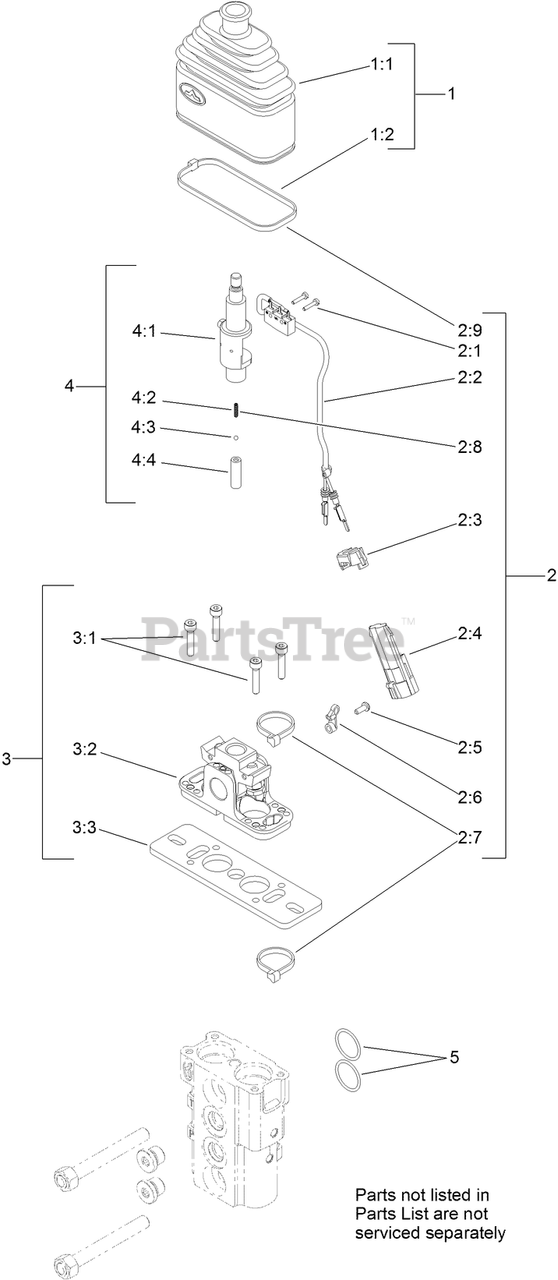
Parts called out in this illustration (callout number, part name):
1	BELLOW KIT
1:1	BELLOW-RUBBER
1:2	HUB and BEARING ASM
2	LIMIT SWITCH KIT
2:1	HUB and BEARING ASM
2:2	Switch
2:3	FAIRLEAD
2:4	Connector
2:5	HUB and BEARING ASM
2:6	HUB and BEARING ASM
2:7	HUB and BEARING ASM
2:8	HUB and BEARING ASM
2:9	HUB and BEARING ASM
3	FULCRUM KIT
3:1	HUB and BEARING ASM
3:2	SUPPORT KIT
3:3	HUB and BEARING ASM
4	SWITCH HOLDER LEVER KIT
4:1	LEVER-HOLDER, SWITCH
4:2	HUB and BEARING ASM
4:3	SPHERE
4:4	HOLDER-SPRING
5	O-RING
